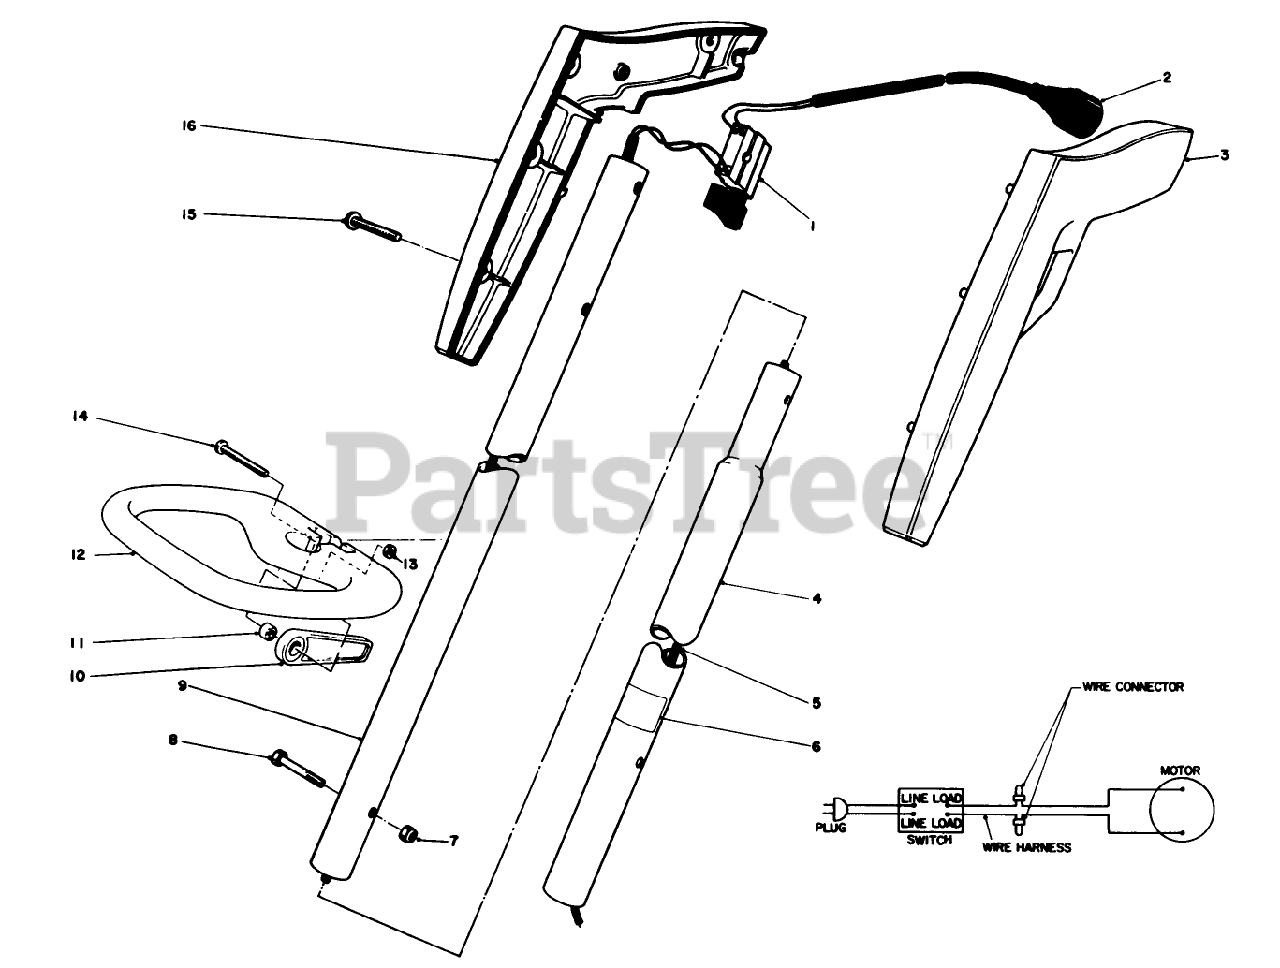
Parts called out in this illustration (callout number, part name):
1	SWITCH SINGLE SPEED
2	Cord-Power
3	Grip L.H.
4	Tubing-Lower Extension
5	Wire Harness
6	REP. SERIAL PLT
7	NUT-LOCK, NI
8	HEX HD MACHINE SCREW
9	Oil Button
10	Cam Lock
11	Spacer
12	Support Handle
13	NUT-HEX
14	Screw
15	Screw
16	R.H. GRIP
